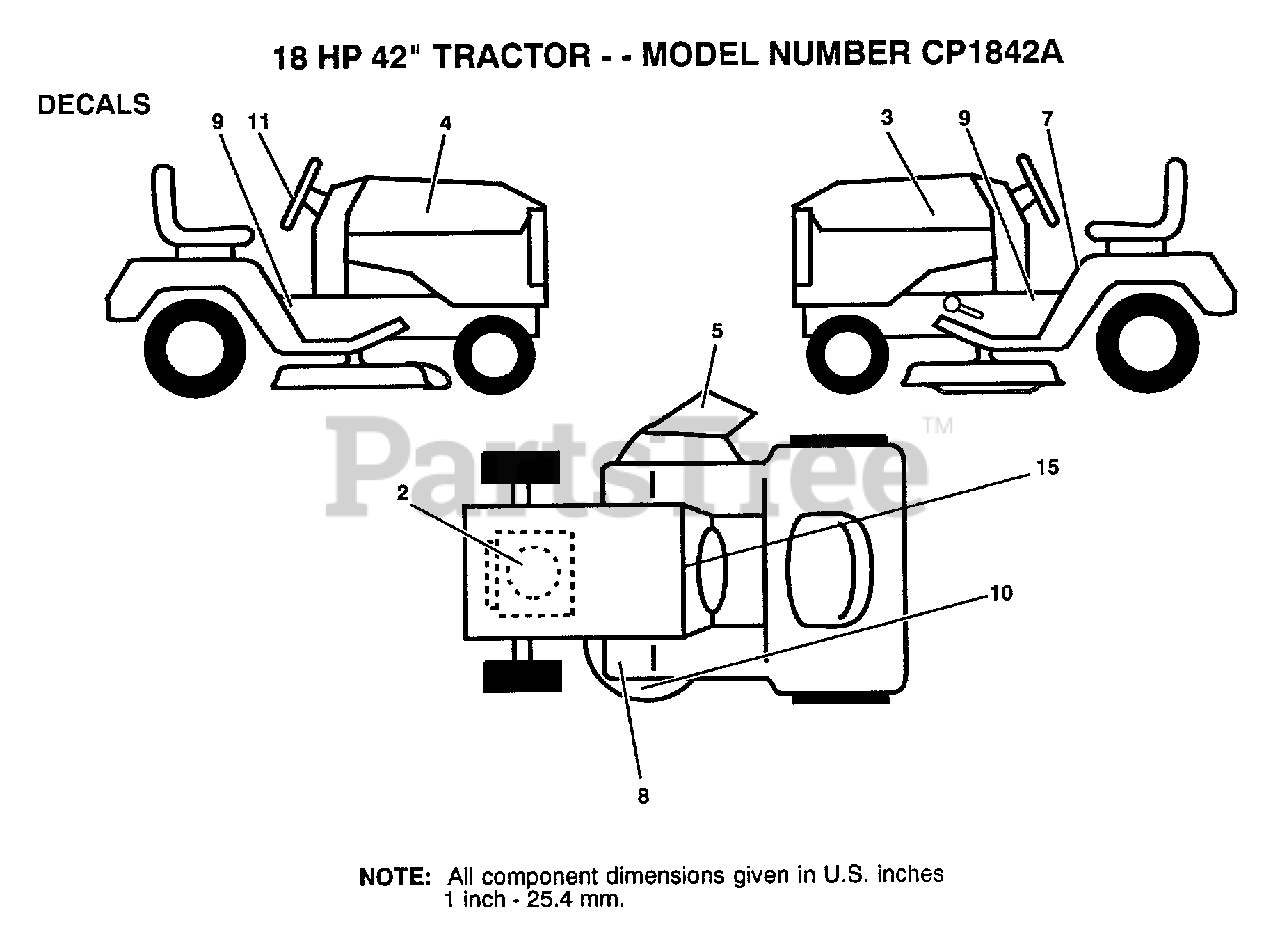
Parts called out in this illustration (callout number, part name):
2	DECAL.ENG.272757
4	DECAL HOOD STRIPE RH
5	DECAL WARING
7	DECAL
9	CHASSIS DECAL
10	DECAL INSTRUCTION CAUTION
11	"DECAL,STRG WHL"
